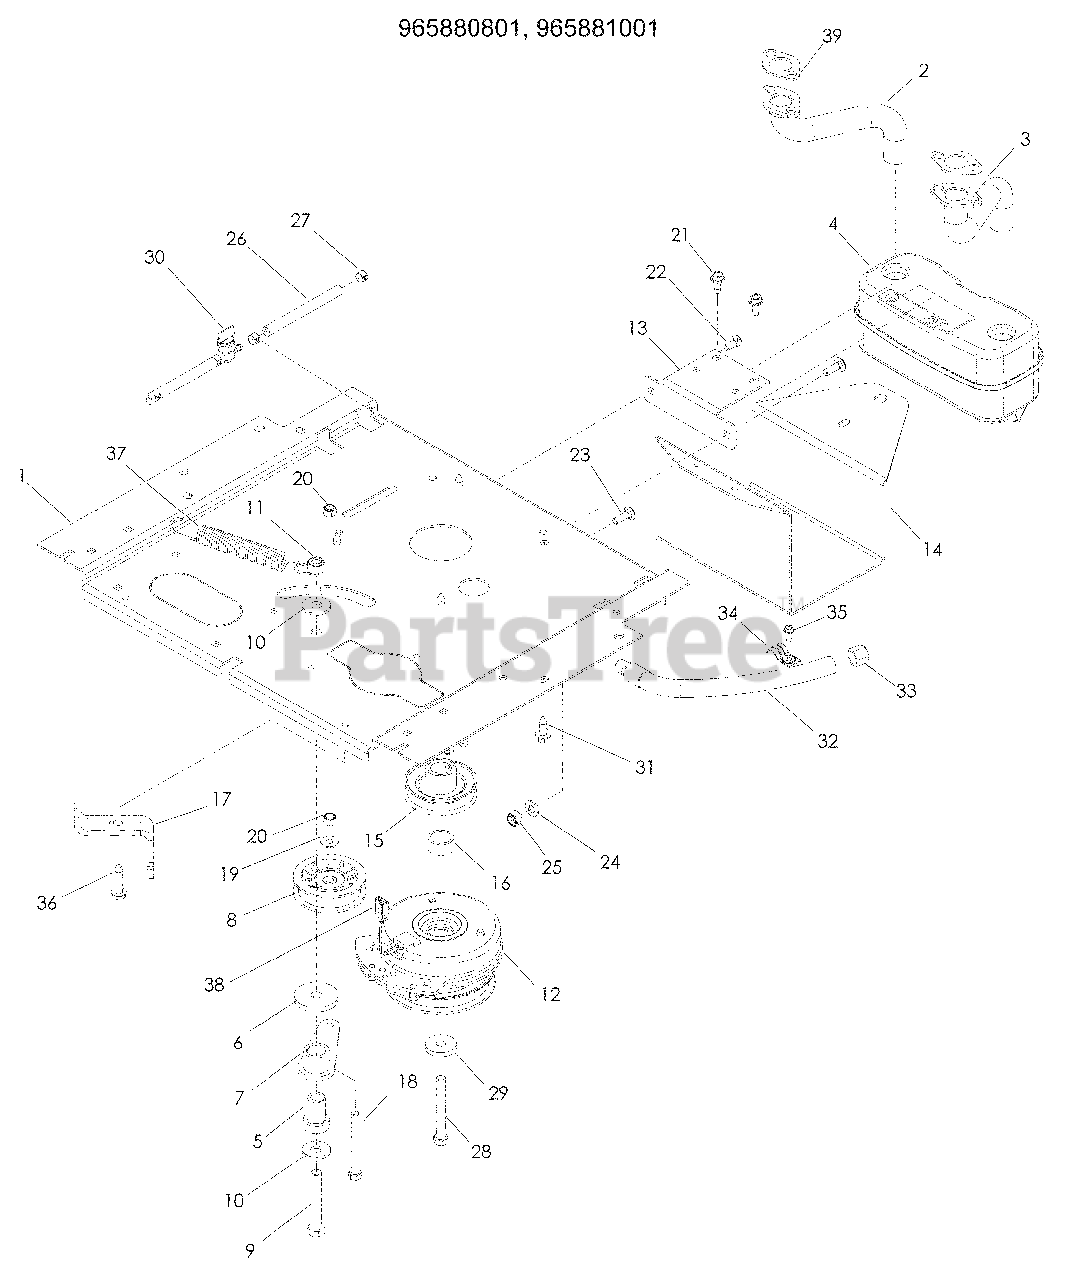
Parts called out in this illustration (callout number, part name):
1	PLATE, ENGINE
2	EXHAUST TUBE, RT
3	EXHAUST TUBE, LT
4	MUFFLER ASM, TWIN
5	SPINDLE, IDLER
6	WASHER, HEAVY
7	IDLER ARM
8	PULLEY, IDLER
9	HCS ½-13 x 3¼
10	WASHER ½ FLAT
11	NUT ½-13 HEX NYLOC
13	BRACKET, MUFFLER
14	GUARD, MUFFLER
15	PULLEY, ENGINE
17	STOP, CLUTCH
18	HCS 3/8-16 x 3½ TPBLT
19	WASHER 5/16 STD FLAT
20	NUT 3/8-16 HEX NYLOC
21	BOLT 5/16-18 x ¾ THD FRM
22	RHSNB 5/16-18 x ¾
23	RHSNB 5/16-18 x 1
24	WASHER 5/16 SAE FLAT
25	NUT 5/16-18 HEX NYLOC
26	FUEL LINE 5"
27	CLAMP, HOSE
28	HCS 7/16-20 x 3½
29	WASHER, CLUTCH
30	VALVE, FUEL
31	HHFS 3/8-16 x 1 THD FRM
32	HOSE, DRAIN
35	SCREW ¼-20 x 5/8 SLF TAP
36	BOLT 3/8-16 x 1½ THD FRM
37	SPRING, DECK DRIVE
38	HARNESS, CLUTCH
39	GASKET, EXHAUST
